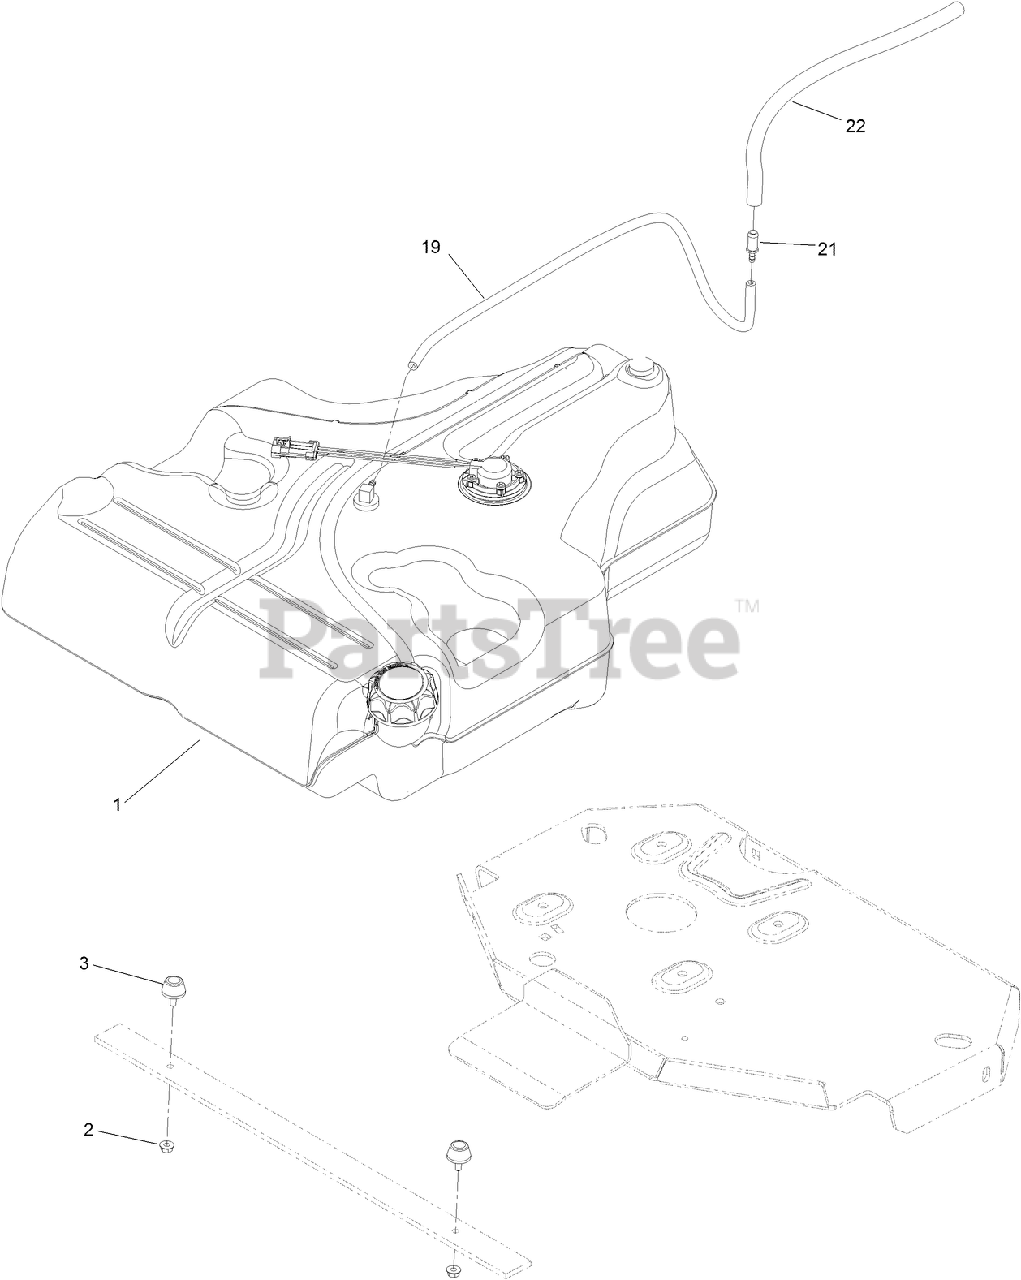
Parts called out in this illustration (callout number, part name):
1	FUEL TANK ASM
2	NUT-JAM
3	BUMPER-RUBBER (W/ STUD)
19	HOSE-FUEL
21	FITTING-STRAIGHT
22	HOSE-FUEL
